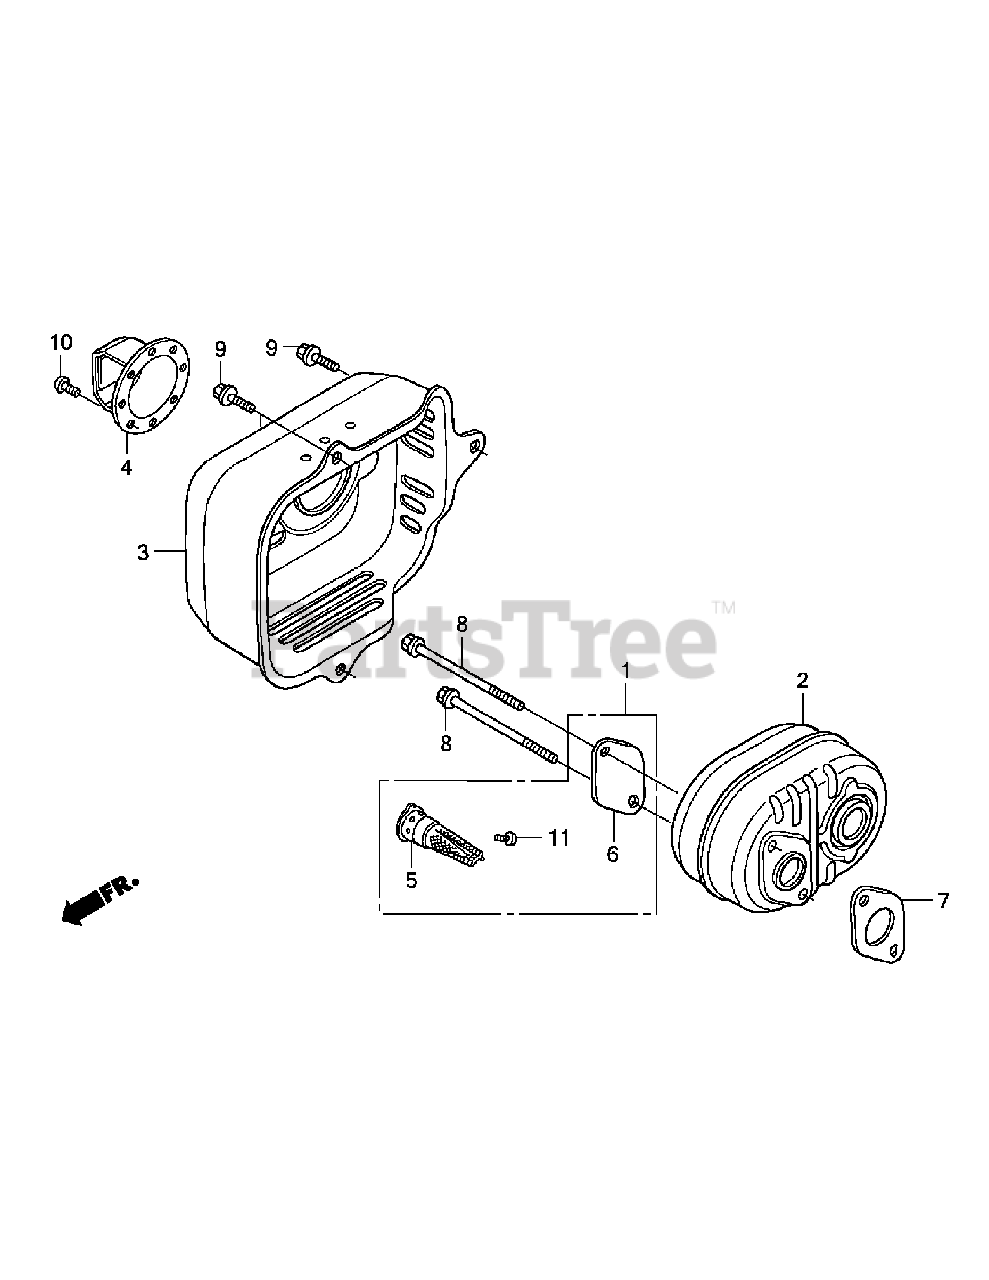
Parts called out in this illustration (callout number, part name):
1	Arrester Kit, Spark
2	Muffler
3	Protector, Muffler
4	Cap, Muffler
5	Arrester, Spark
6	Plate, Arrester Number
7	Gasket, Muffler
8	Bolt, Flange (6x79) (Ct200)
9	Bolt, Flange (6x12) (Ct200)
10	Screw, Tapping (4x6)
11	Screw, Tapping (4x6)
